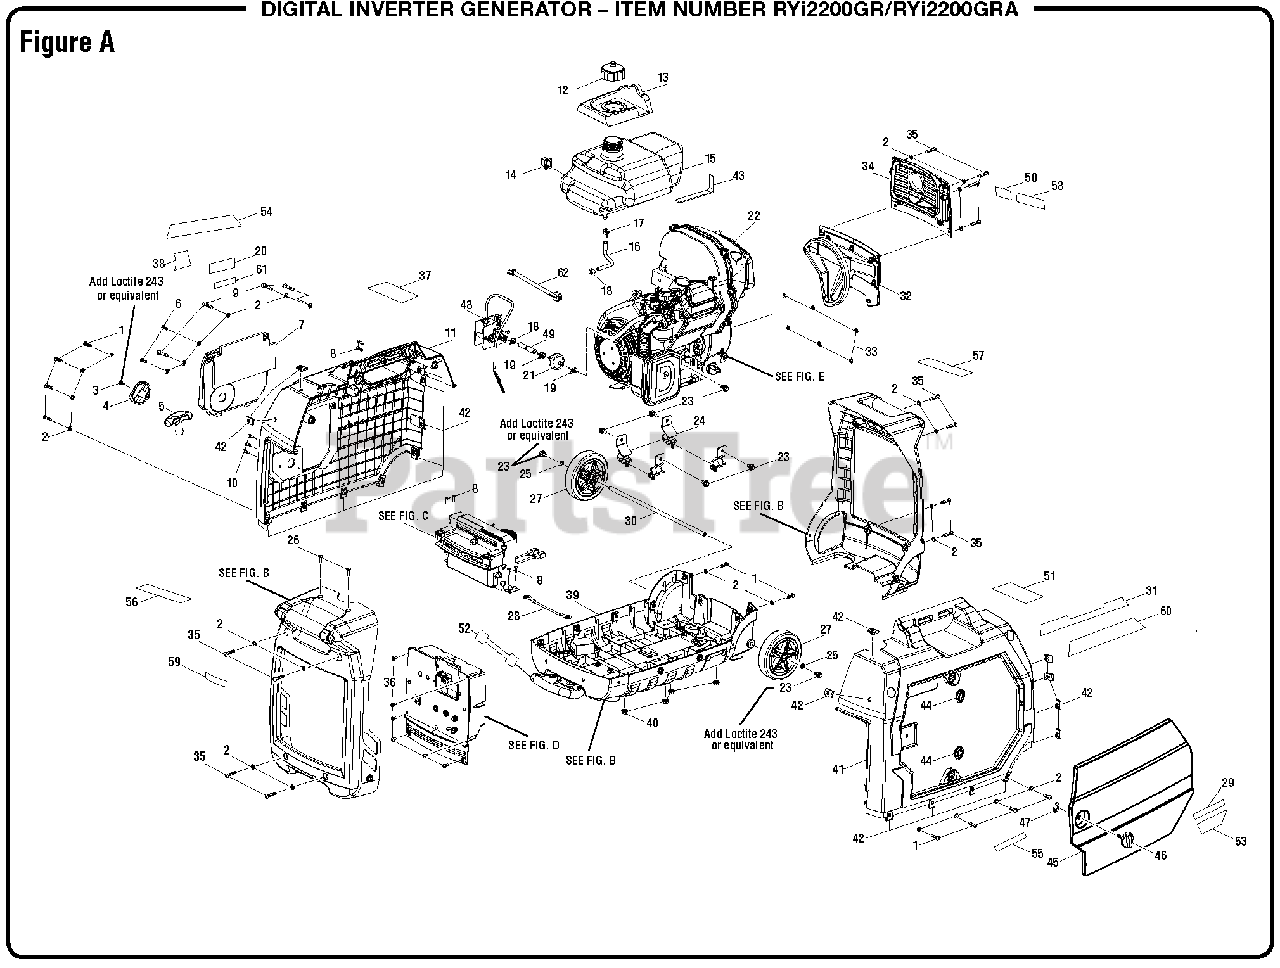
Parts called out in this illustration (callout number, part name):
1	Screw (M5 x 20 mm, Button Soc. Hd.)
2	Washer (M5.3)
3	Screw (M4 x 10 mm)
4	Control Knob
5	Recoil Handle
6	Screw (M5 x 12 mm, Button Soc. Hd.)
7	Starter Cover Assembly
8	Screw (M4 x 12 mm, T15 Torx Hd.)
9	Screw (M5 x 30 mm, Phillips Hd.)
10	Screw (M4 x 16 mm, Flat Hd.)
11	Left Housing Assembly
12	Vented Fuel Cap
13	Overspill Guard
14	Fuel Tank Support
15	Fuel System Assembly
16	Fuel Hose (6mm and 4.5 mm)
17	Clamp (10 mm)
18	Fuel Hose Clamp (3/8 in.)
19	Fuel Hose Clamp (9.5 mm)
20	Easy Start Logo Label
21	Fuel Filter
22	Engine (Ducar) (See Figure E)
23	Bolt (M6 x 12 mm, Hex Hd.)
24	Engine Isolator (45 Degree)
25	Lock Washer
26	Screw (M5 x 16 mm, Flat Hd.)
28	Ground Wire
29	Inquiries Label
31	Fire Distance Label
32	Lower Exhaust Panel Assembly
33	Washer (5 mm)
34	Upper Exhaust Panel Assembly
35	Screw (M5 x 25 mm, Button Soc. Hd.)
36	Screw w/Washer (M4 x 10 mm, T20 Torx Hd.)
37	Danger Label
38	Choke Label
39	Bottom Base Assembly
40	Lock Nut (M6)
41	Right Housing Assembly
42	U-Clip (M5)
43	Rubber Pad
45	Maintenance Cover Assembly
46	Lock Knob
47	Retaining Ring
48	Engine Start/Stop Mechanism Assembly
49	Fuel Hose (4.5 mm and 6 mm)
50	Combustion Label
51	CPSC Label
52	Handle Release Label
53	Lubricant Label
54	Performance Label
55	Maintenance Label
56	Fuel Stabilizer Label
57	Ground Warning Label (English/French)
58	Hot Surface Label
59	Logo Label
60	Performance Label (Maintenance Door)
61	Start Label
62	Engine Wire Harnes
